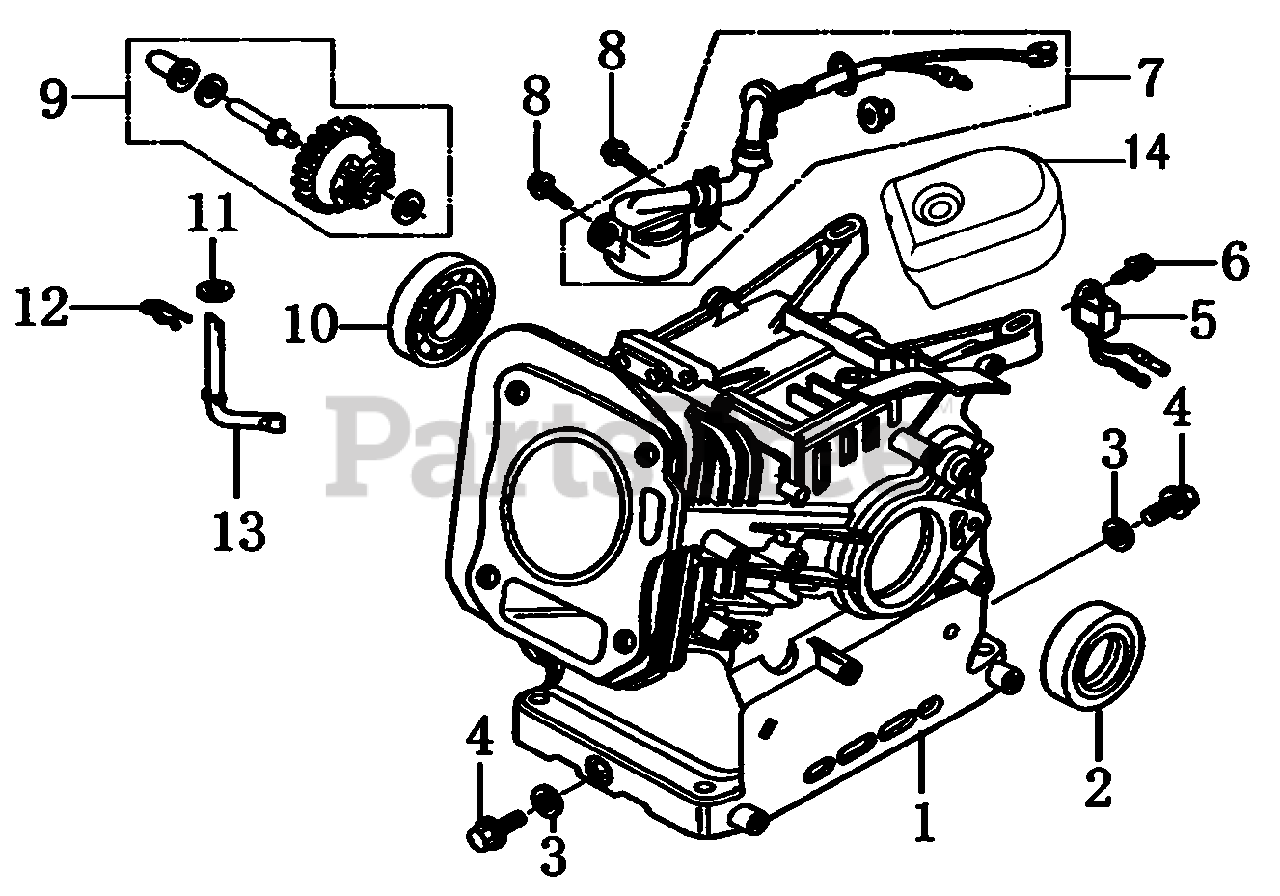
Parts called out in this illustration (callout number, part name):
1	CRANK CASE
2	OIL SEAL 25×41.25×6
3	WASHER, DRAIN PLUG
4	BOLT, DRAIN PLUG
5	ALERT UNIT, OIL
6	BOLT, FLANGE, 6×10
7	OIL LEVEL SWITCH
8	BOLT, FLANGE , 6*14
9	GOVERNOR GEAR ASSY.
10	BEARING, RADIAL BALL
11	WASHER, PLAIN
12	PIN, LOCK
13	SHAFT, GOVERNOR ARM
14	COVER, WIRE
